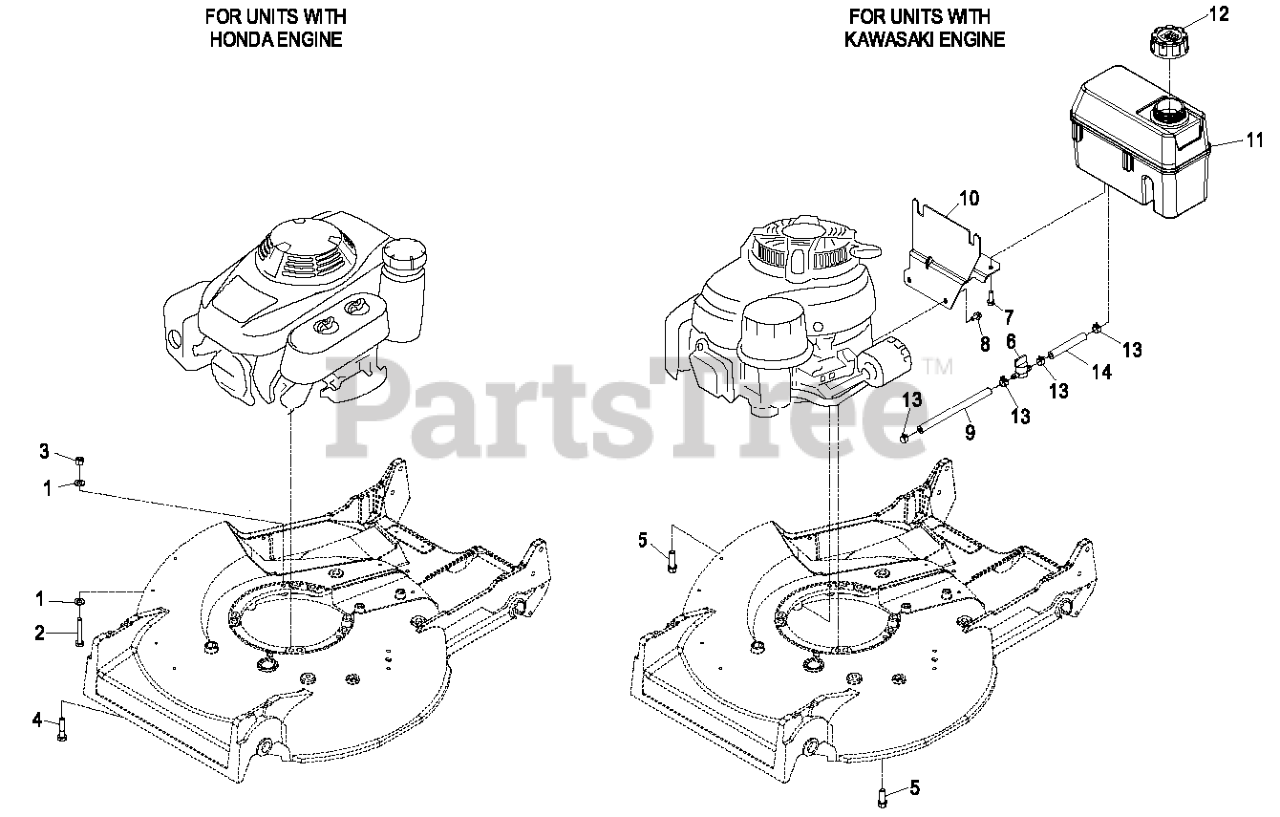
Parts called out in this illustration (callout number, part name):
1	WASHER-PLAIN
2	SCREW-HH
3	NUT-LOCK, NI
4	SCREW-SHOULDER
5	SCREW-TAPTITE
6	VALVE-FUEL
7	SCREW-HWH
8	SCREW-HWH
9	HOSE-FUEL
12	CAP-GAS
13	CLAMP-HOSE
14	HOSE-FUEL
